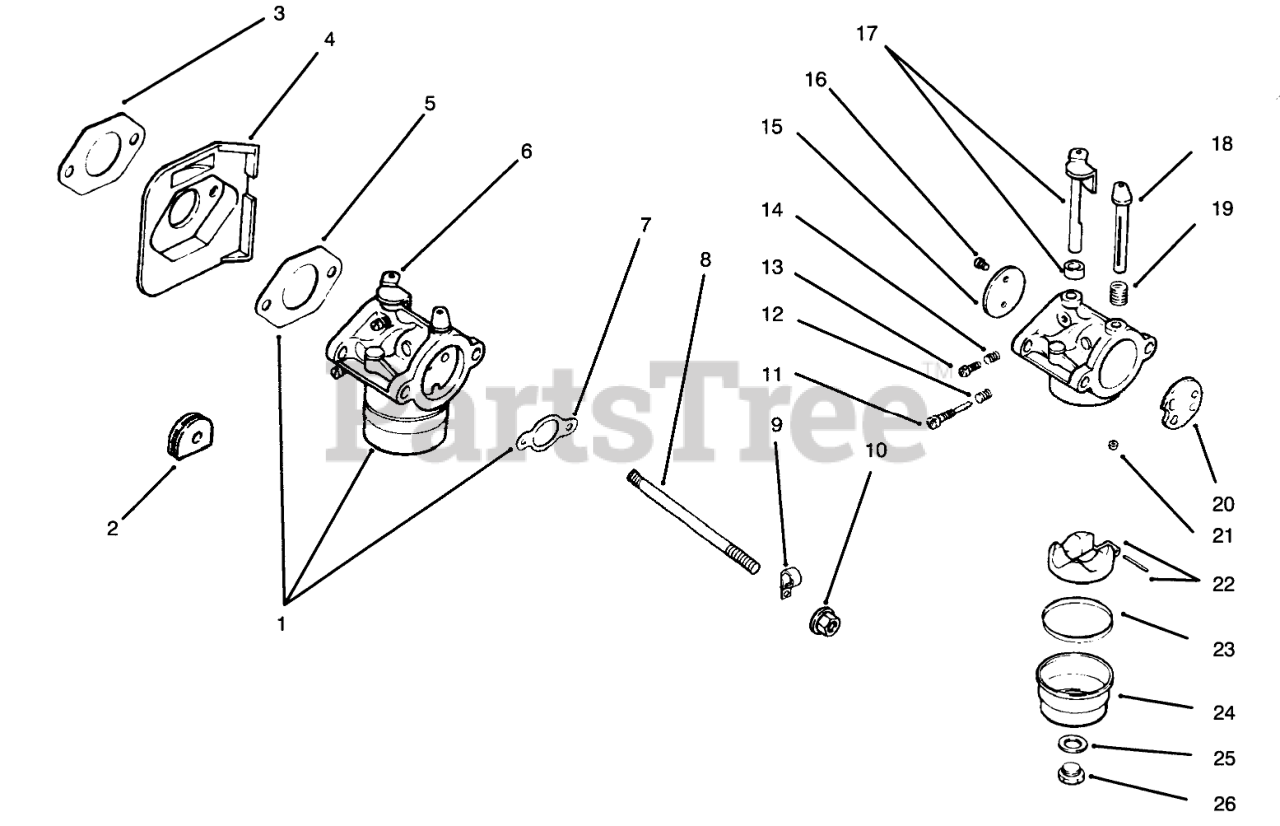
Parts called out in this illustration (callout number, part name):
1	Kit-Carburetor
2	Grommet
3	Gasket
4	Deflector
5	Carburetor Assembly(Ref.)
6	Gasket
7	Gasket
11	Needle-Idle
12	Spring-Idle
13	Screw-Idle
14	Spring-Idle
15	Plate-Throttle
16	Screw-Throttle Plate
17	Shaft-Throttle
18	Shaft-Choke
19	Spring
20	Plate-Choke
21	Jet-Main
22	Kit-Float
23	Gasket-Bowl
24	Bowl
25	Gasket
26	Screw-Bowl
